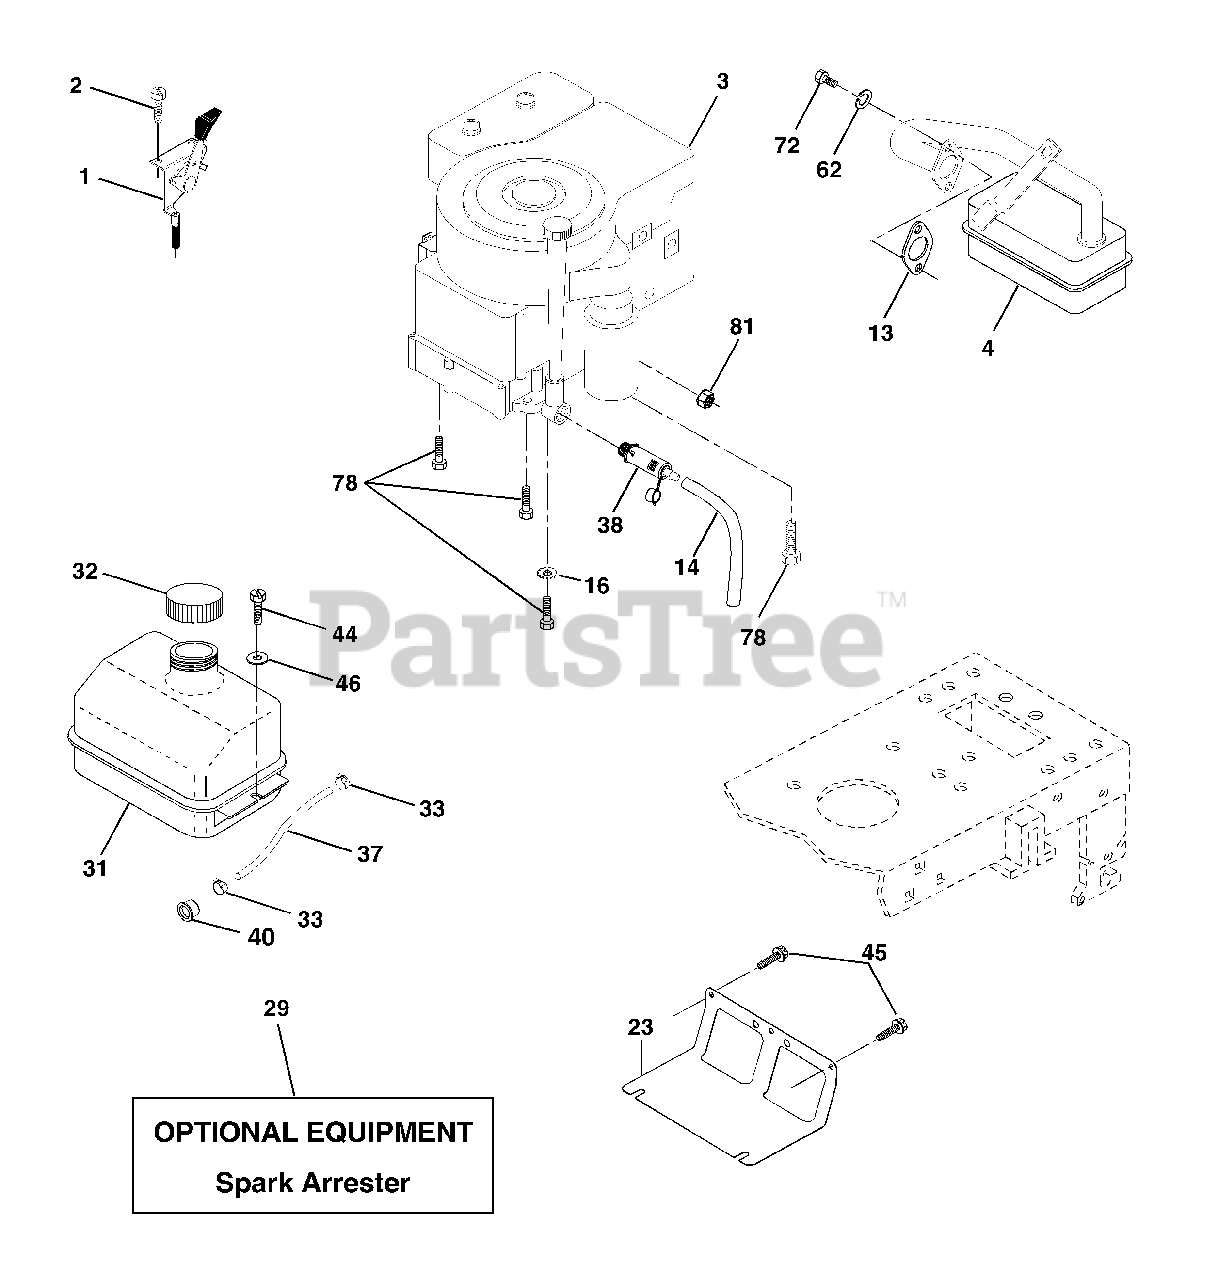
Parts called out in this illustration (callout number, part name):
1	Control Throt /Ch Flag
2	Screw Hex Thd Cut 1/4-20x1/2
4	Muffler Exhaust B&S Lt
13	Gasket 1 313 Id Tin Plated
14	Tube Drain Oil Easy
16	Washer Lock Ext Tooth 3/8
23	Shield Browning/Debris Guard
29	Arrestor Spark
31	Tank Fuel 1 25 Fr
32	Cap Asm Fuel W/sym Vented
33	Clamp Hose Blk
37	Line Fuel 20"
38	Plug Drain Oil Easy
40	Bushing Snap Nyl Blk Fuel Line
44	Screw Hexwsh Thdrol 1/4-20x3/4
45	Screw Hex Wsh Thdrol 3/8-16
46	Washer 9/32 X 7/8 X 16ga
62	Washer Lock Hvy Hlcl Spr 5/16
72	Screw Hexhd Cap 5/16-18x3/4
78	Screw Thdrol 3/8-16x1-1/4
81	Nut Keps Hex 1/4-20 Unc
